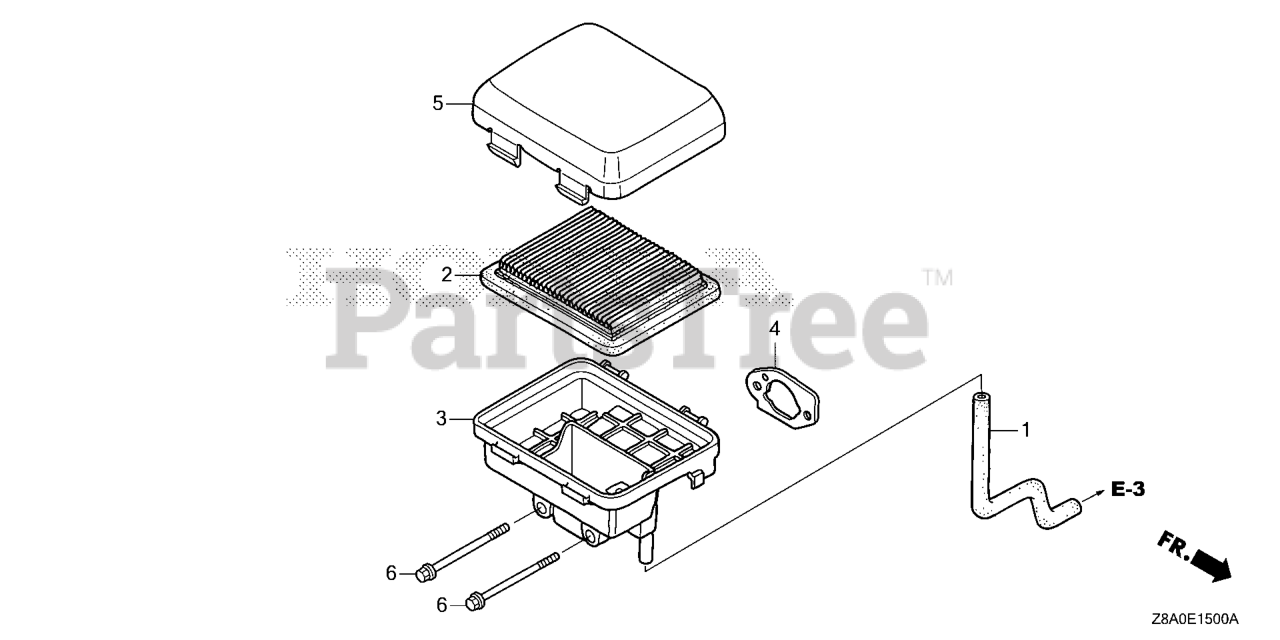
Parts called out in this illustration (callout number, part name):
1	TUBE, BREATHER
2	ELEMENT, AIR CLEANER (TOYO ROKI) (ENGINE NO.)
3	HOUSING, AIR CLEANER
4	GASKET, AIR CLEANER
5	COVER, AIR CLEANER
6	BOLT, FLANGE (6X112) (CT200)
